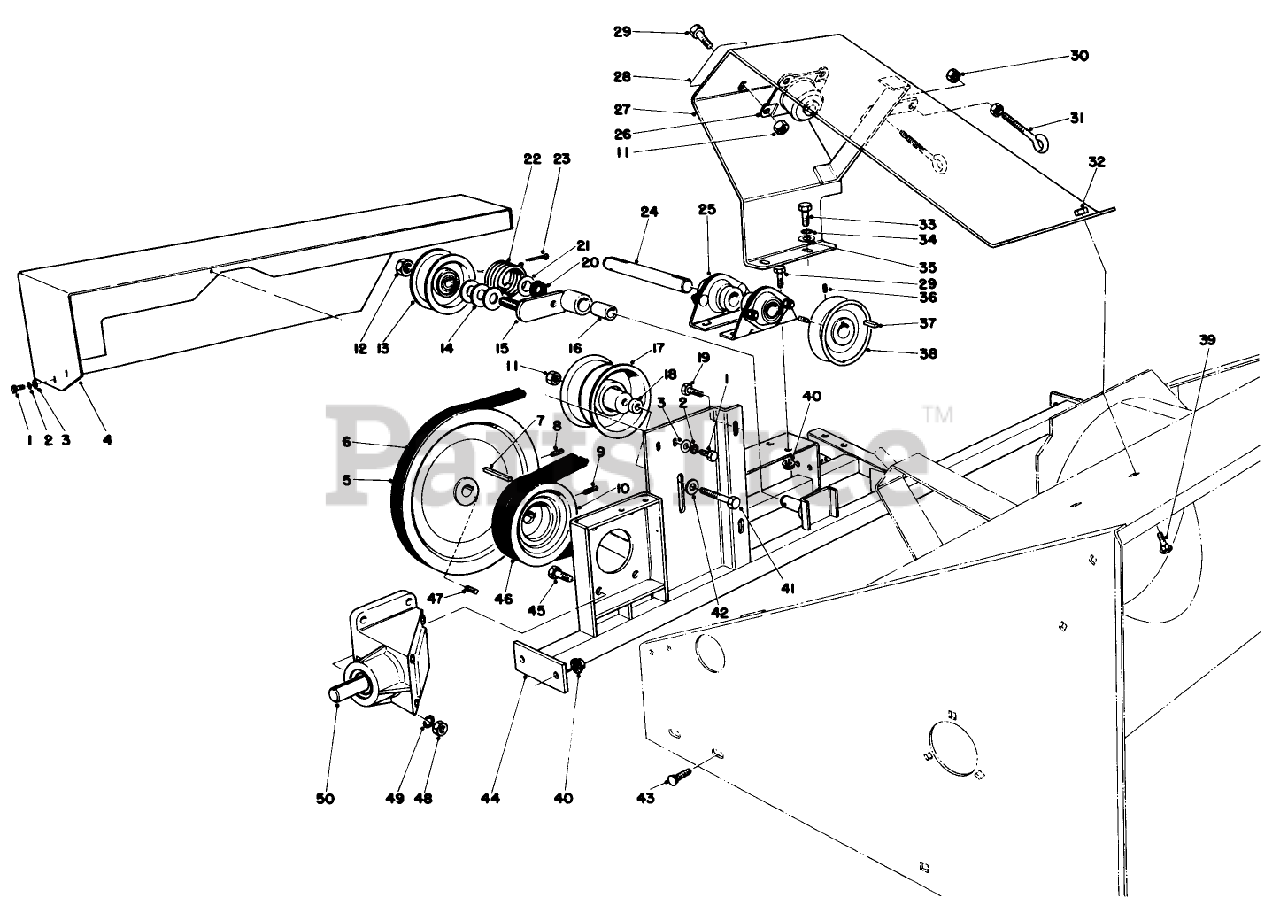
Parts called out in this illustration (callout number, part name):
1	SCREW-HH
2	WASHER-LOCK
3	WASHER-FLAT
4	BELT SHIELD WA
5	SHEAVE 60014
6	V-BELT
8	SCREW-SQH
9	SCREW-SET, SQH
10	PULLEY
11	NUT-LOCK, CONE
12	LOCKNUT 6239
13	Flat Idler
14	WASHER-FLAT
15	Idler Arm (Incl.Ref.#30)
16	BUSHING 16162
17	Idler Pulley
18	IDLER SPACER
19	SCREW-HH
20	Felt Washer
21	Washer
22	Spring-Torsion
23	PIN-COTTER
24	JACKSHAFT
25	Bearing
26	Flange Bearing
27	Bearing Support
28	Decal-Chute Rotation
29	SCREW-HH
30	NUT-JAM
31	Eyebolt
32	NUT-LOCK, NI
33	SCREW-HH
34	WASHER-LOCK
35	WASHER-FLAT
36	5/16-18 X 1/2 SQ HD
38	SHEAVE 60103
39	BOLT-CARR
40	NUT-HHF, WHIZ
41	SCREW-HH
42	WASHER-FLAT
43	SCREW-CARR
44	Cross Brace
45	SCREW-HH
46	V-BELT
47	SCREW-SET, SQH
48	NUT-HEX
49	WASHER-LOCK
50	Gear Box Assembly
